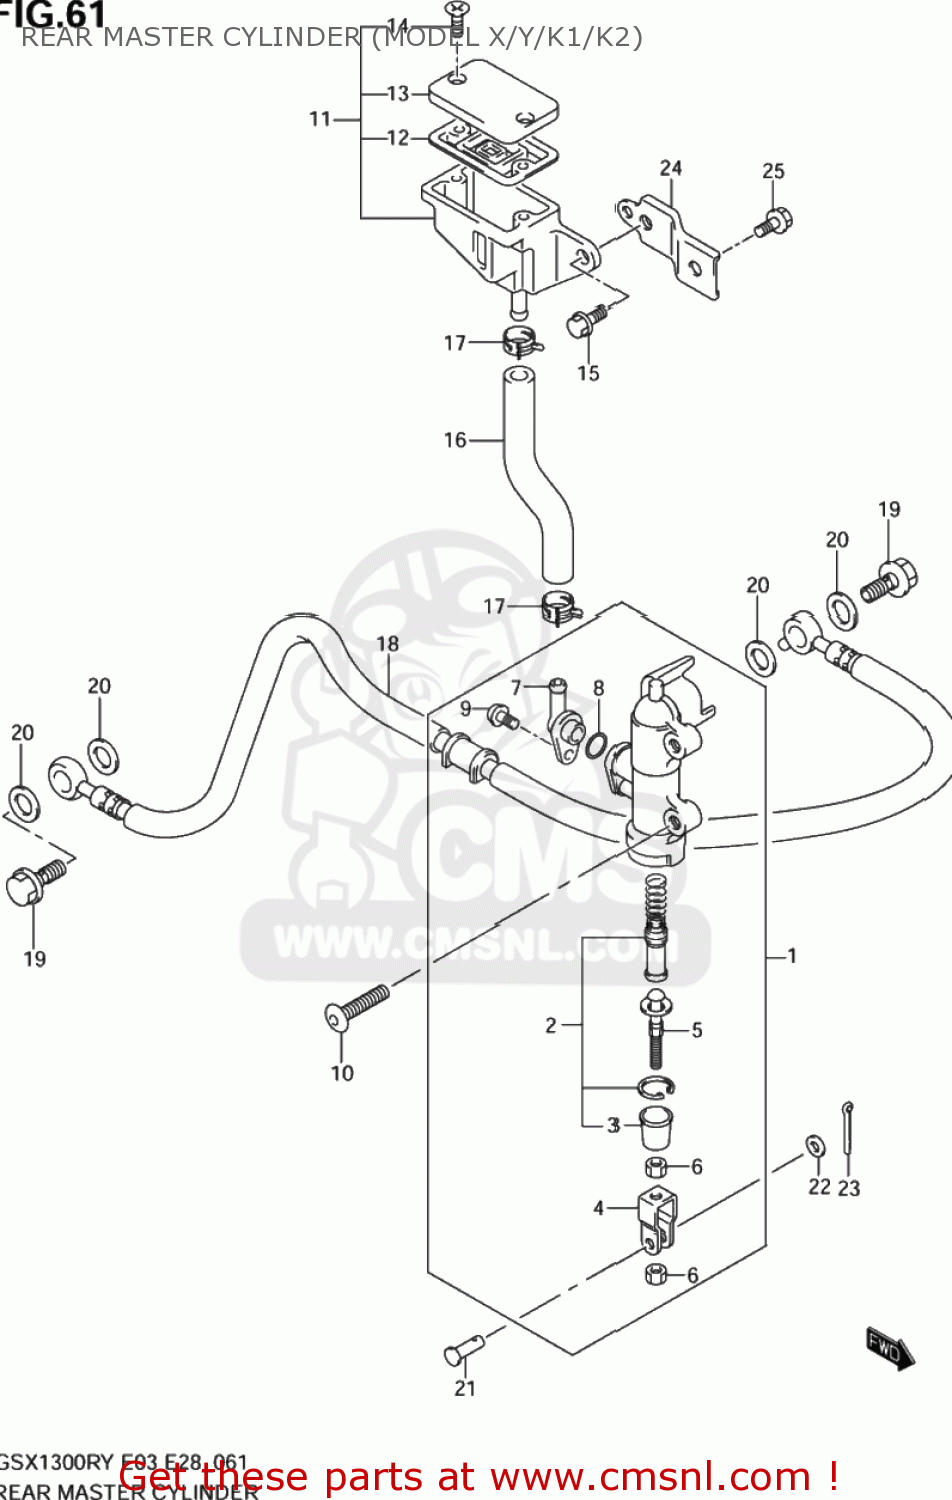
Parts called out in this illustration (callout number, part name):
1	CYLINDER ASSY,RR MASTER
2	PISTON/CUP SET
3	BOOT
4	YOKE
5	ROD,PUSH
6	NUT
7	CONNECTOR
8	O RING
9	SCREW
10	SCREW(6X20)
11	TANK ASSY,RR RESERVOIR
12	DIAPHRAGM
13	CAP
14	SCREW
15	BOLT
16	HOSE,RESERVOIR TANK
17	CLIP
18	HOSE,REAR BRAKE
19	BOLT UNION
20	WASHER(10X15X1.5)
21	PIN
22	WASHER
23	PIN
24	BRACKET,RR RESERVOIR TANK
25	BOLT
